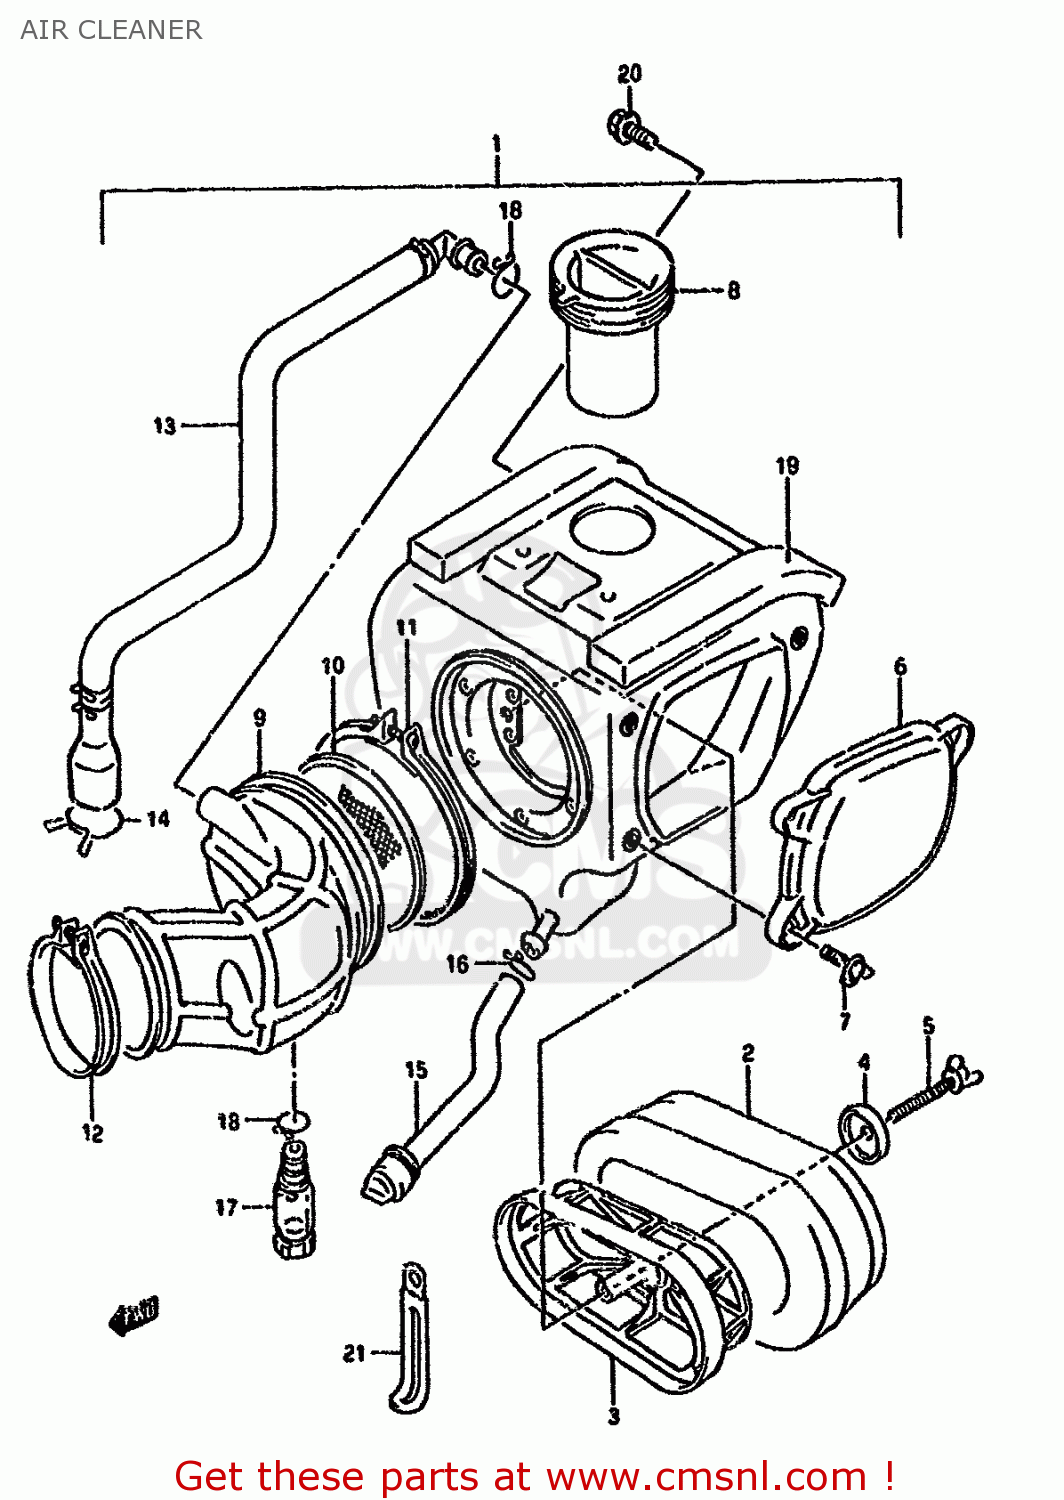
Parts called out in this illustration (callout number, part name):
1	CLEANER ASSEMBLY,AIR
2	FILTER
3	HOLDER,FILTER
4	WASHER,AIR CLEANER
5	BOLT,WING
6	CAP,AIR CLEANER
7	SCREW
8	TUBE,INLET
9	TUBE,OUTLET
10	TRAP,FRAME
11	CLAMP
12	CLAMP
13	TUBE,BREATHER
14	CLIP
15	TUBE,DRAIN A
16	CLIP
17	TUBE,DRAIN B
18	CLIP
19	CUSHION
20	BOLT
21	CLAMP
